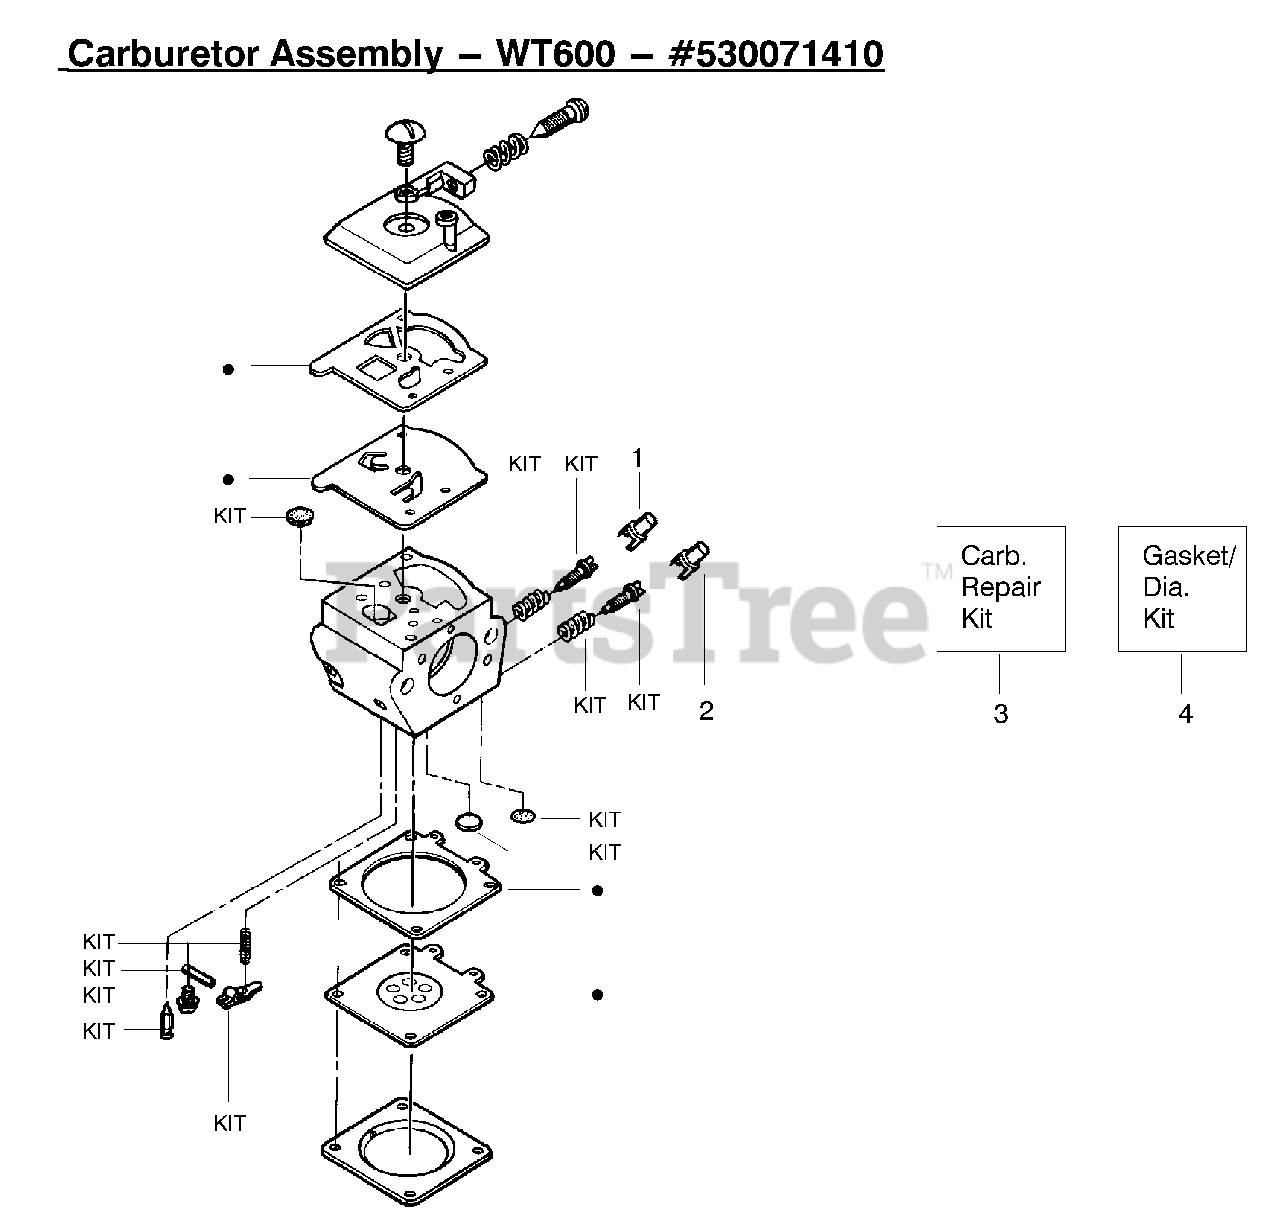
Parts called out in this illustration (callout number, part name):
1	Limiter Cap-High
2	Limiter Cap-Low
3	Carburetor Repair Kit
4	Gasket Diaphragm Kit
